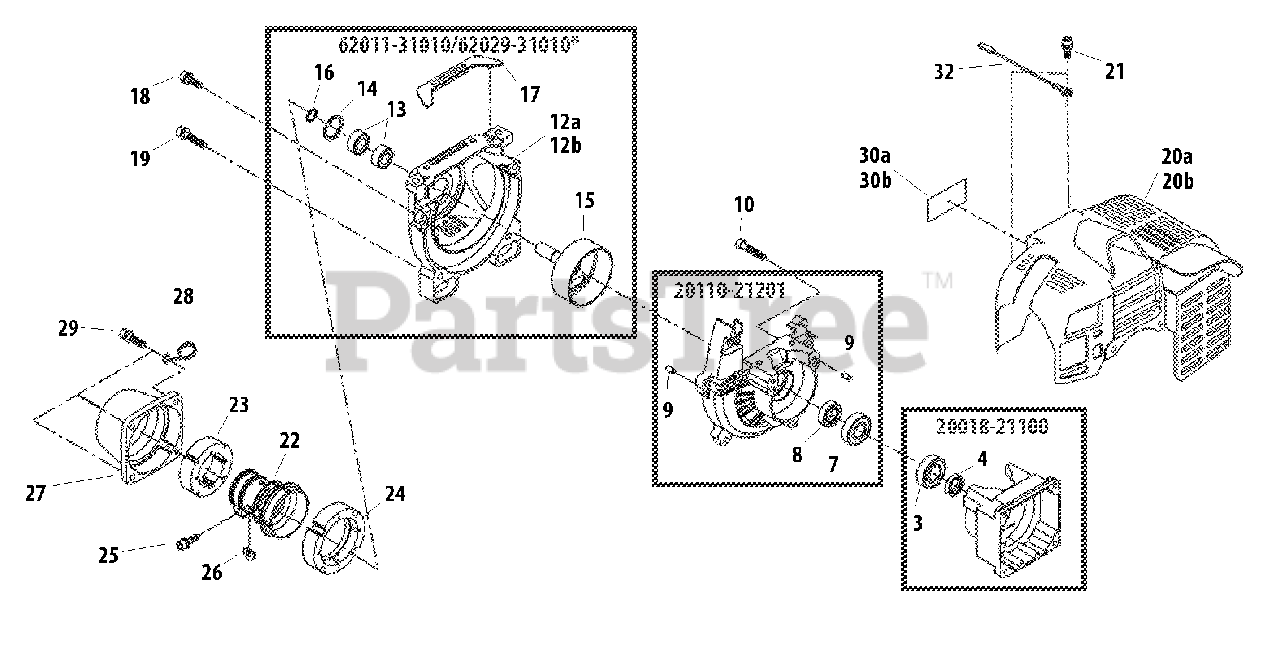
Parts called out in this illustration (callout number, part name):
3	BEARING, BALL - 6001C3
4	SEAL, OIL
7	BEARING, BALL - 6001C3
8	SEAL, OIL - 12
9	PIN - LOCATING
10	SCREW - 5X25
12A	CASE, FAN - RED
12B	CASE, FAN - BLUE
13	BEARING, BALL - 6000DDU
14	RING, RETAINING - 26
15	DRUM, CLUTCH
16	RING, RETAINING
18	SCREW - 5X16
19	SCREW - 5X25
20A	COVER, ENGINE - RED
20B	COVER, ENGINE - BLUE
21	SCREW - 5X16
22	CLAMP, MAIN PIPE
23	CUSHION - FRONT
24	CUSHION - REAR
25	SCREW - 5X25
26	SHIM
27	CAP
28	GUIDE, CABLE
29	SCREW - 5X20
30A	LABEL - MODEL
30B	LABEL - MODEL
32	LEAD - GROUND
20018-21100	CRANKCASE ASSY - REAR
20110-21201	CRANKCASE ASSY - FRONT
62011-31010	FAN CASE ASSY - RED
62029-31010	FAN CASE ASSY - BLUE
